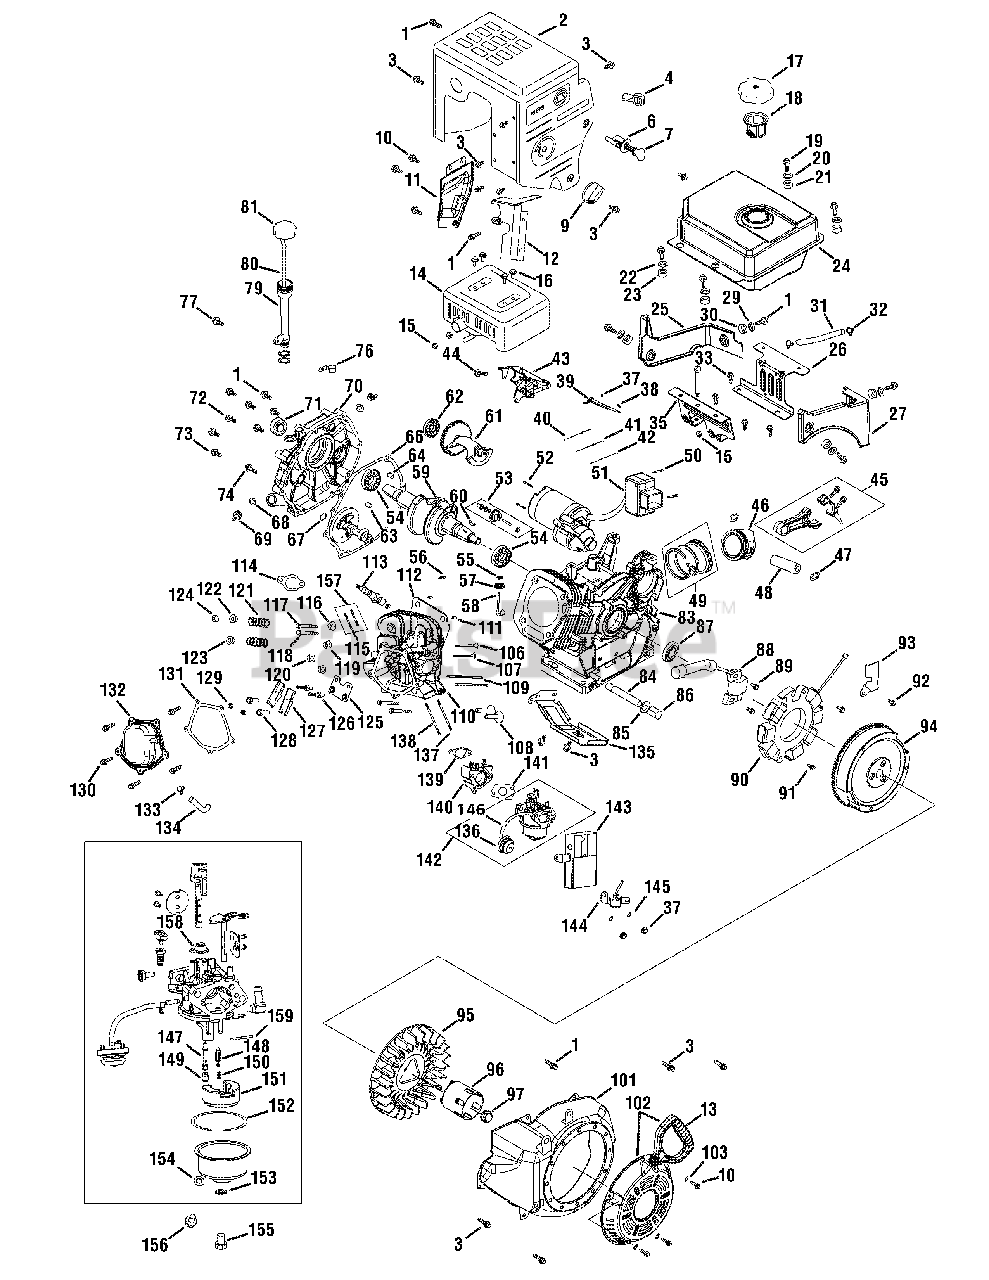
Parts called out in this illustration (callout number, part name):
1	Bolt, M6 x 16
2	Muffler Shield
3	Bolt, M6 x 12, Zinc Coating
4	Throttle Control Knob
6	Ignition Switch Assembly
7	Key
9	Choke Knob
10	Bolt, Flange, M6 x 10
11	Muffler Baffle
12	Carburetor Heat Shield
13	Starter Handle
14	Muffler Assembly
15	Nut, M8 x 1.25
17	Fuel Cap
18	Fuel Filter
19	Flange Bolt, M8 x 20
20	Flat Washer
22	Flat Washer
25	Fuel Tank Shroud
26	Fuel Tank Mounting Bracket
27	Engine Shroud
29	Flat Washer
31	Fuel Line
32	Fuel Line Clamp
33	Bolt, Flange, M8 x 14
35	Fuel Tank Mounting Bracket
37	Nut, Flange, M6
38	Bolt, M6 x 21, Governor Arm
39	Governor Arm Bracket
40	Governor Spring
41	Throttle Return Spring
42	Governor Rod
43	Throttle Control Assembly
44	Bolt, Flange, M6 x 14
45	Connecting Rod Ass’y Complete
46	Piston
47	Piston Pin Clip
48	Piston Pin
49	Piston Ring Set - Complete
50	Screw, M4 x 55
51	Electric Starter
52	Flange Bolt, M8 x 55
53	Governor Assembly
54	Bearing
55	Governor Shaft Washer
56	Governor Shaft Clip
57	Oil Seal - Governor Shaft
58	Governor Arm Shaft
59	Crankshaft Assembly
60	Flywheel Key
61	Camshaft Assembly
62	Bearing
63	Dowel Pin
64	Dowel Pin, 7 x 14
66	Crankcase Cover Gasket
67	Washer
68	O-Ring
69	Oil Fill Plug
70	Crankcase Cover
71	Oil Seal - PTO Side
72	Flange Bolt, M8 x 38
73	Bolt, M8 x 45
74	Bolt, M8 x 35
76	Oil Tube Support Bracket
77	Flange Bolt M6 x 16
79	Dipstick Tube
80	Dipstick
81	Oil Cap
83	Crankcase
84	Oil Drain Pipe
85	Oil Drain Washer
86	Oil Drain Plug
87	Oil Seal - Flywheel Side
87	Oil Seal- Flywheel Side
88	Ignition Coil
89	Bolt, Flange, M6 x 28
91	Flange Bolt, M6 x 30
92	Flange Bolt, M6 x 8
93	Alternator Wire Clamp Bracket
95	Cooling Fan
96	Starter Cup
97	Nut, M16 x 1.5
99	Bolt, M6 x 12
101	Blower Housing
102	Recoil Starter Assembly
103	Flat Washer Recoil
106	Exhaust Valve
107	Intake Valve
108	Valve Lifter (Tappet)
109	Push Rod
110	Cylinder Head
111	Dowel Pin, 12 x 20
112	Cylinder Head Gasket
113	Spark Plug
114	Muffler Gasket
115	Exhaust Stud
116	Flex Washer
117	Head Bolt
118	Bolt, M10 x 1.25 x 87
119	Intake Valve Seal
120	Valve Spring Retainer
121	Valve Spring
122	Valve Spring Retainers - Exhaust
123	Valve Spring Retainer- Intake
124	Exhaust Valve Cap
125	Push Rod Guide
126	Rocker Stud Bolt
127	Rocker Arm
128	Pivot Adjusting Nut
129	Pivot Locking Nut
130	Bolt - Valve Cover, M6 x 16
131	Valve Cover Gasket
132	Valve Cover
133	Breather Hose Clip
134	Breather Hose
135	Cylinder Baffle
136	Primer
137	Carburetor Stud, M6 x 8 x 98
138	Carburetor Stud, M6 x 8 x 118
139	Carb Insulator Gasket
140	Carburetor Insulator
141	Carburetor Gasket
142	Carburetor Assembly
143	Heater Box
144	Choke Assembly
145	Lock Washer
146	Primer Hose
147	Main Nozzle
148	Needle Valve
149	Main Jet
150	Needle Valve Spring
151	Float
152	Bowl Gasket
153	Fuel Bowl Gasket
154	Fuel Drain Plug Gasket
155	Fuel Bowl Mounting Bolt
156	Fuel Drain Plug
157	Exhaust Stud Assembly
158	Throttle Pressure Plate
159	Float Pin
